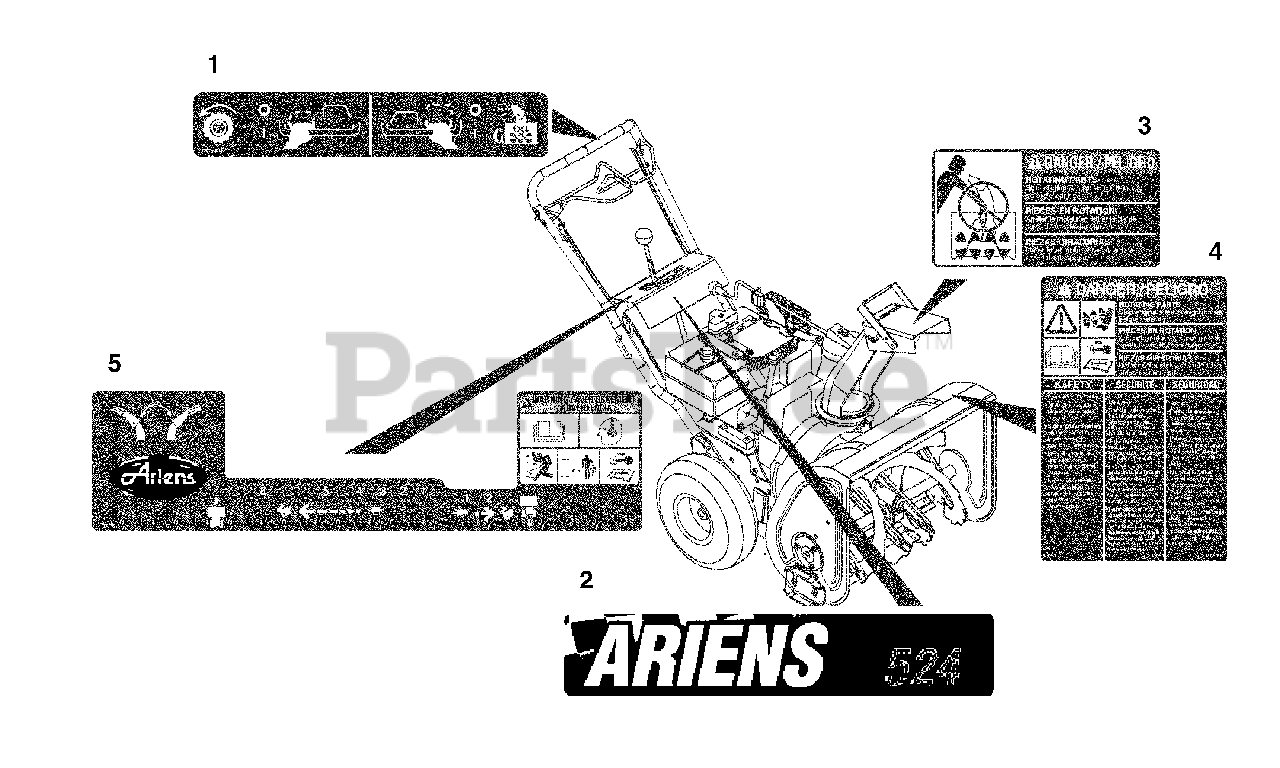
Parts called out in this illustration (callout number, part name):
1	DECAL, BAIL
2	DECAL, ST524
3	DECAL, DANGER - ROT. PARTS
4	DECAL, DANGER
5	DECAL, CONTROL PANEL
